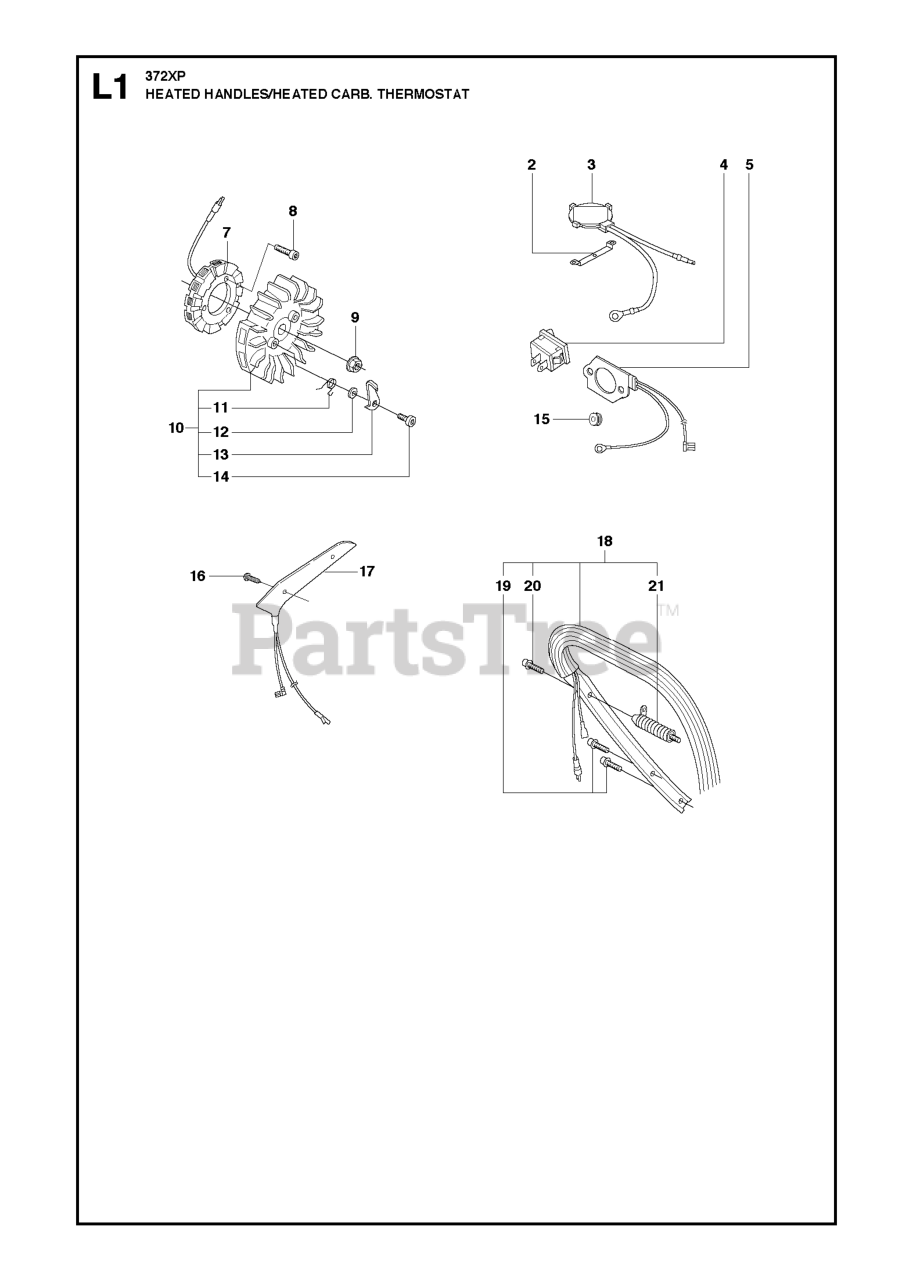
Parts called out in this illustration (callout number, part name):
3	THERMOSTAT
5	FOIL ELEMENT
9	NUT W/ WASHER
14	SCREW
18	FRONT HANDLE (G)
19	SCREW IHSCFT PW5.5X16 8.8 ZN/
20	SCREW ITXSCFT PW6.3X22 T27 8.
21	ANTIVIBRATION ELEMENT
